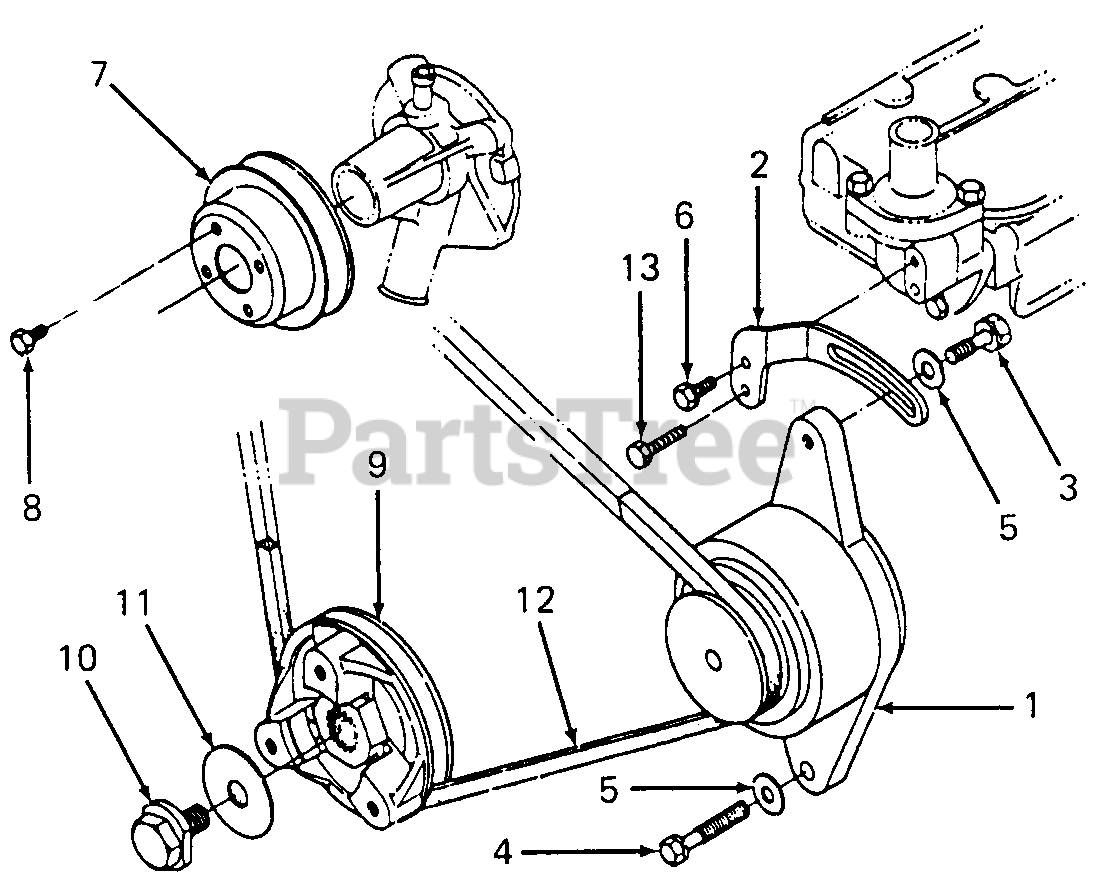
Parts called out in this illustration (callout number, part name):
1	Alternator
2	Support, Alternator
3	Screw w/Washer
4	Screw w/Washer
6	Screw w/Washer
7	Pulley, Water Pump
8	Screw, Hex Washer Head
9	Pulley, Alternator Drive
13	Screw w/Washer
